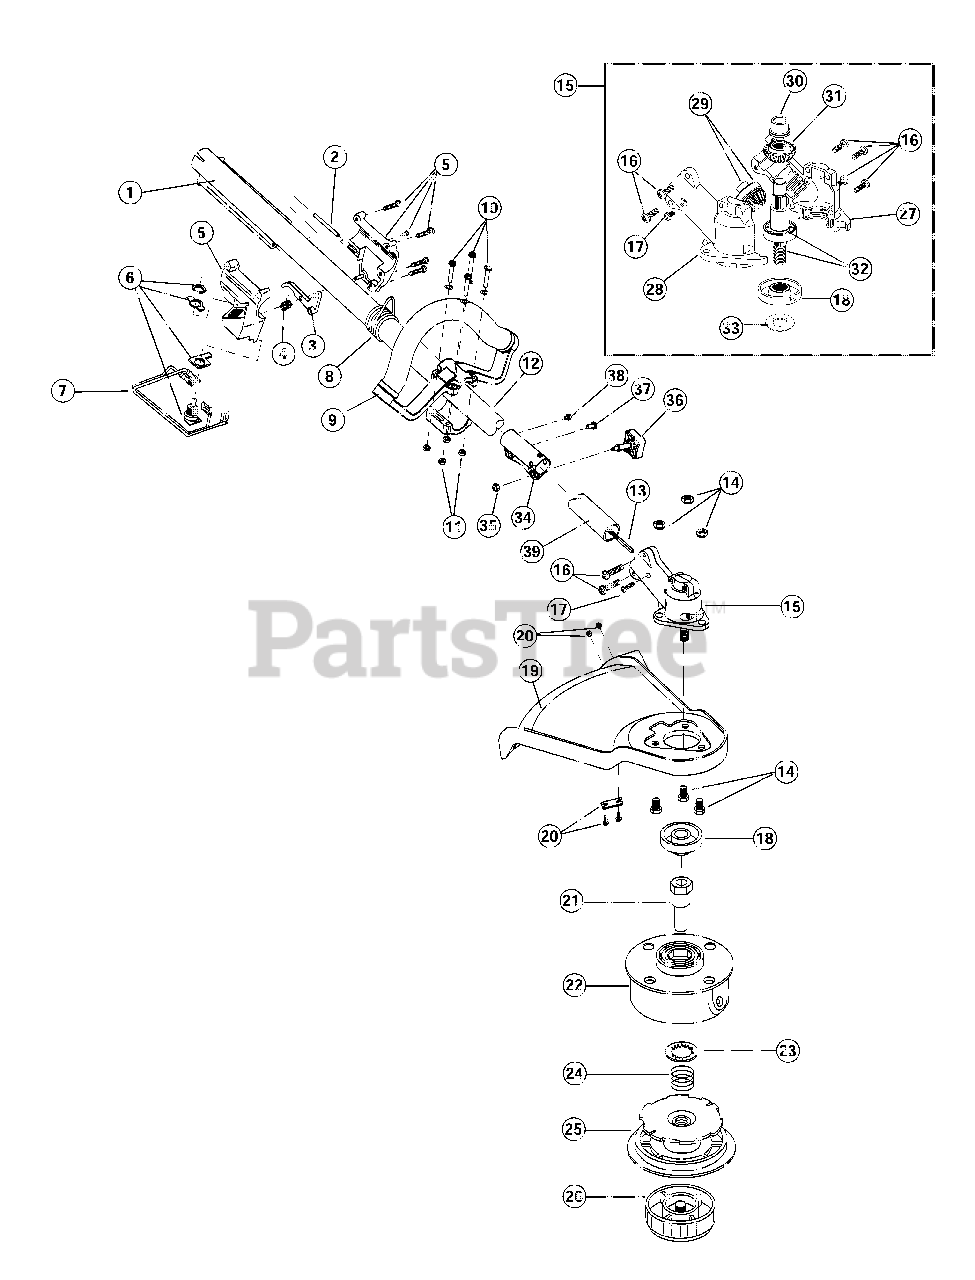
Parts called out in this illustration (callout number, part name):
2	Throttle Cable Assembly
3	Throttle Trigger
4	Throttle Trigger Spring
5	Throttle Trigger Assembly
6	Switch Assembly
7	Wire Lead Assembly
8	Shoulder Harness Clamp
9	Handle Assembly
11	Nut
12	Drive Shaft Housing Assembly
13	Lower Drive Shaft
14	Shield Mount Screw Assembly
15	2 piece Gearbox Assembly
16	Gearbox Mounting Hardware
17	Anti-Rotation Screw
18	Blade Driver
19	Shield and Blade Assembly
20	Blade Assembly
21	Spool Shaft
22	Outer Spool Assembly
23	Retainer
26	Bump Head Knob Assembly
27	Left Housing
28	Right Housing
29	Pinion Gear Assembly
30	Output Shaft Bushing
31	Output Shaft Gear
32	Output Shaft Assembly
33	Palnut
34	Split Boom Coupler Assmbly
35	Nut
36	Knob
37	Bolt
38	Screw
39	Lower Boom Assembly
